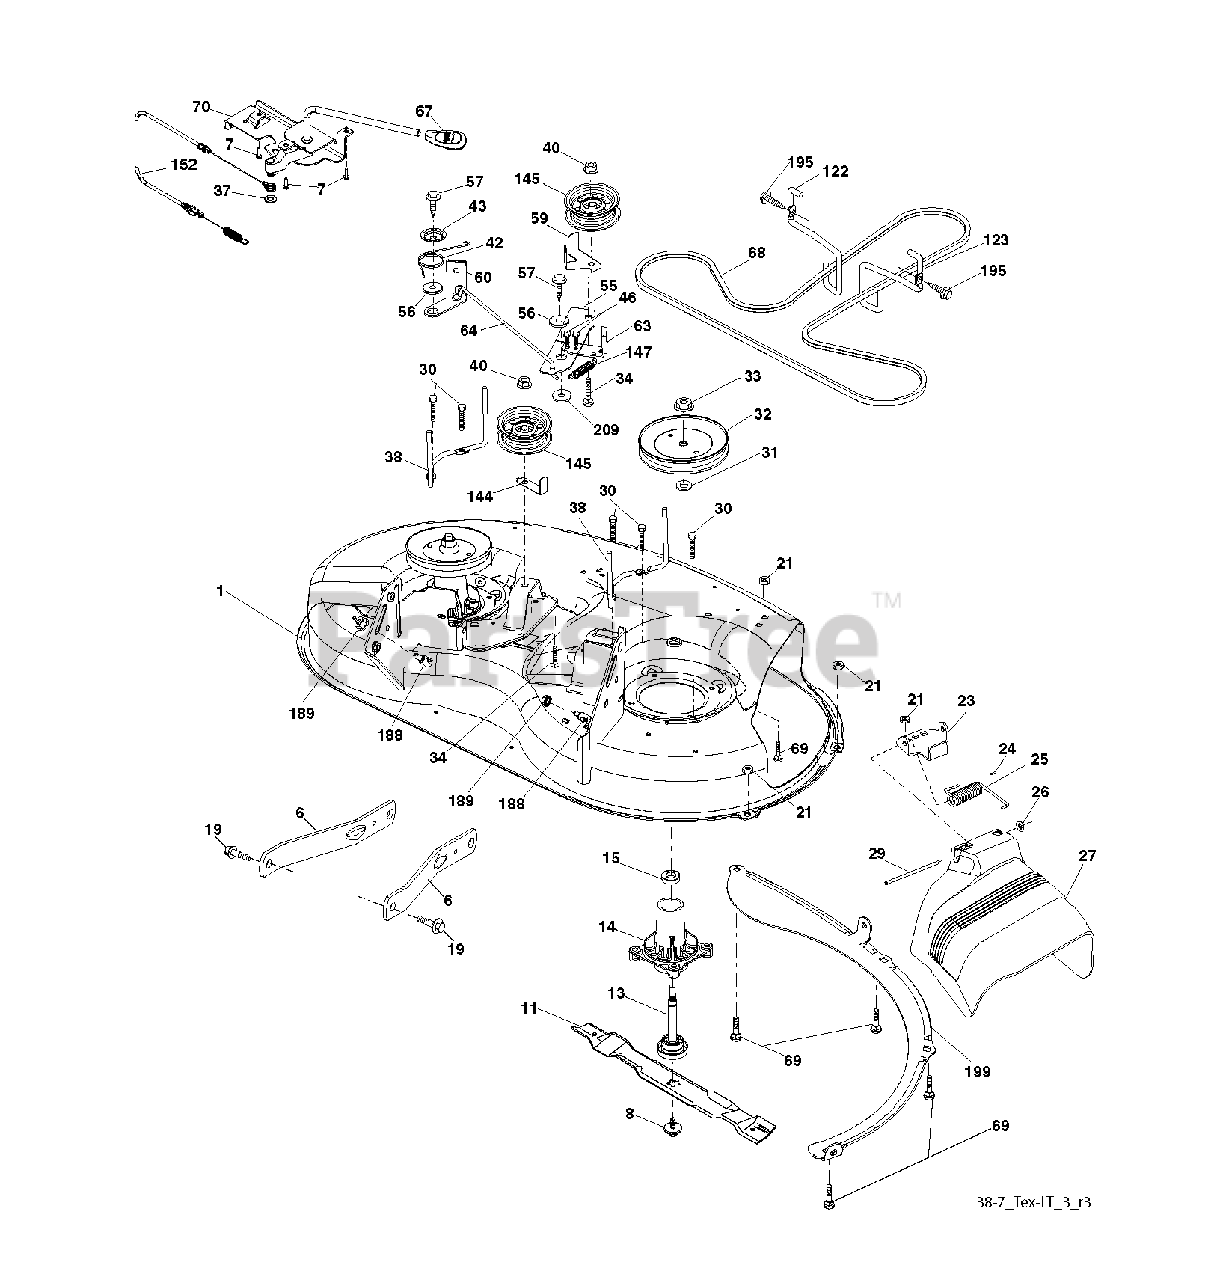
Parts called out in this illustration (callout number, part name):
6	ARM.SUSPENSION.MOWER.R
7	SCREW.#10 X 0.750.BOS THREAD
8	BOLT.WASHER.ASM.7/16-2
11	BLADE 38" PREMIUM
13	SHAFT.ASM.MDRL.N/GREASE.38
14	HOUSING MANDREL
19	BOLT.SHOULDER
21	LOCKNUT
23	BRKT.DEFLECTOR.38"2005+
24	CAP-SLEEVE LT
25	SPRING.TORSION.DEFLECT
26	NUT PUSH M
29	ROD.HINGE
30	SCREW, WASHER HEAD
31	WASHER.SPACER.MANDREL
32	PULLEY.MANDREL.5.0.PD.38"
33	NUT.FLANGE.LOCK.TOP
34	BOLT.3/8-16X1.50
38	KEEPER BELT LH MANDREL
40	NUT LOCK FLG 3/8-16 UNC
42	SPRING.TORSION.BRAKE
43	SRPING.TORSION.RETAINE
46	SCREW.1/4-20X5/8
55	IDLER.ARM
56	SPACER.RETAINER
57	SCREW 3/8-16X1
59	GUARD, BELT
60	ARM BRAKE MOWER RH 38"
63	ARM BRAKE MOWER RH
64	LINK BRAKE
67	HANDLE.CLUTCH.CABLE.LT
69	BOLT
70	CLUTCH.ASM.MANUAL.LT.PRED
122	KEEPER BELT ENGINE LH
123	KEEPER BELT RH
144	KEEPER BELT
145	PULLEY.IDLER.48"PRIMARY
147	SPRING RETURN
152	CLUTCH CABLE
188	STUD.FASTNER.W/ANTI-ROTATE
189	NUT LOCK HEX FLANGE 5/16-18
195	SCREW, 3/8-16X3/4
199	BAFFLE VORTEX
209	WASHER 12/32X2X10GA
